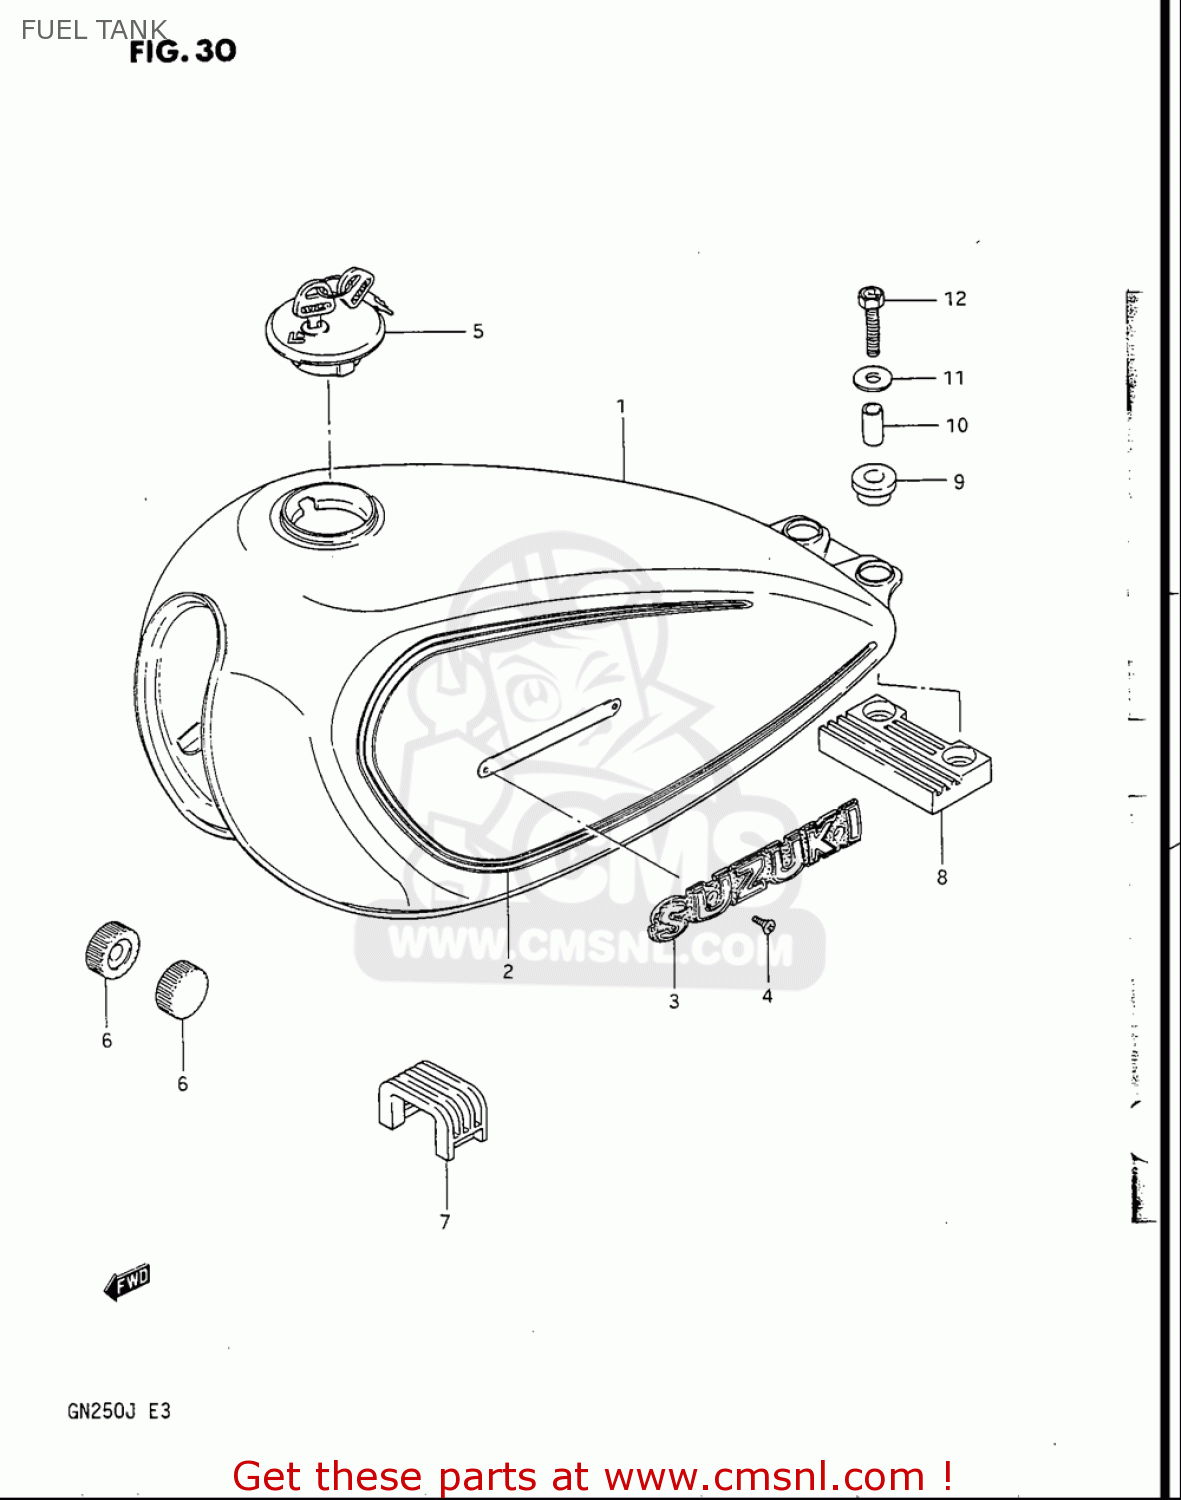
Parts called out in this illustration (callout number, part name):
1	TANK ASSEMBLY,FUEL
2	TAPE SET,FUEL TANK
3	EMBLEM,FUEL TANK
4	SCREW
5	CAP SET,FUEL TANK
6	CUSHION
8	CUSHION,TANK RR NO.1
9	CUSHION
10	SPACER(6.5X10.5X22.5)
11	WASHER(6.5X22X1.6)
12	BOLT(6X35)
